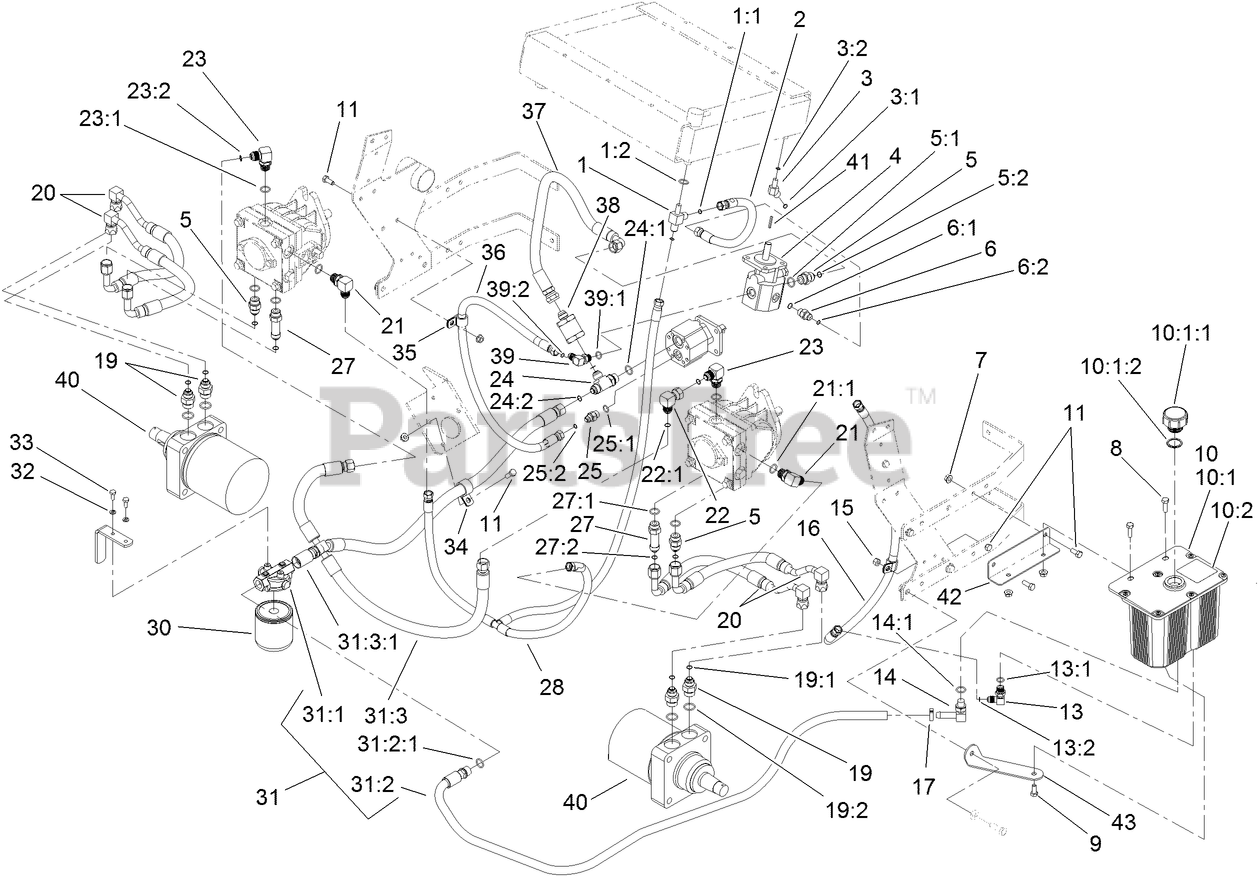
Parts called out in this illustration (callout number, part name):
1	FITTING-HYD, STRAIGHT TEE
1:1	O-RING
1:2	O-RING
2	FAN CASE DRAIN HOSE ASM
3	FITTING-HYD, 45 ELBOW
3:1	O-RING
3:2	O-RING
4	MOTOR-FAN, COOLING
5	FITTING-STRAIGHT
5:1	O-RING
5:2	O-RING
6	FITTING-STRAIGHT
6:1	O-RING
6:2	O-RING
7	NUT-HF
8	SCREW-HH
9	SCREW-HH
10	HYDRAULIC TANK ASM
10:1	Deck ASM
10:1:1	CAP-RESERVOIR, HYD
10:1:2	GASKET-CAP
10:2	DECAL-TANK, HYD
11	SCREW-HH
13	FITTING-90 DEG
13:2	O-RING
14	FITTING-ELBOW, 90 DEG
14:1	O-RING
15	NUT-LOCK, NI
16	TANK RETURN HOSE ASM
17	CLAMP-HOSE
19	FITTING-STRAIGHT
19:1	O-RING
19:2	O-RING
20	HYD HOSE ASM
21	FITTING-ELBOW, 90 DEG
21:1	O-RING
22	FITTING-90 DEG
22:1	O-RING
23	FITTING-90 DEG
23:1	O-RING
23:2	O-RING
24	FITTING-TEE
24:1	O-RING
24:2	O-RING
25	FITTING-STRAIGHT
25:2	O-RING
27	ADAPTER-STR, LONG
27:1	O-RING
27:2	O-RING
28	CASE DRAIN HOSE ASM
30	FILTER-OIL, HYDRAULIC
31	CHARGE HOSE ASM
31:1	HEAD-FILTER
31:2	FILTER INLET HOSE ASM
31:2:1	O-RING
31:3	PUMP INLET HOSE ASM
31:3:1	O-RING
32	WASHER-LOCK
33	SCREW-HH
34	CLIP-LOOM
35	CLIP-LOOM
36	AUXILLARY PUMP HOSE ASM
37	HOSE-PRESSURE, HIGH
38	FILTER-IN LINE, 50 MICRON
39	FITTING-90 DEG
39:2	O-RING
40	MOTOR-WHEEL, HYD
41	KEY-SQUARE
42	BRACKET-TANK MOUNT, UPPER
43	BRACKET-TANK MOUNT, LOWER
